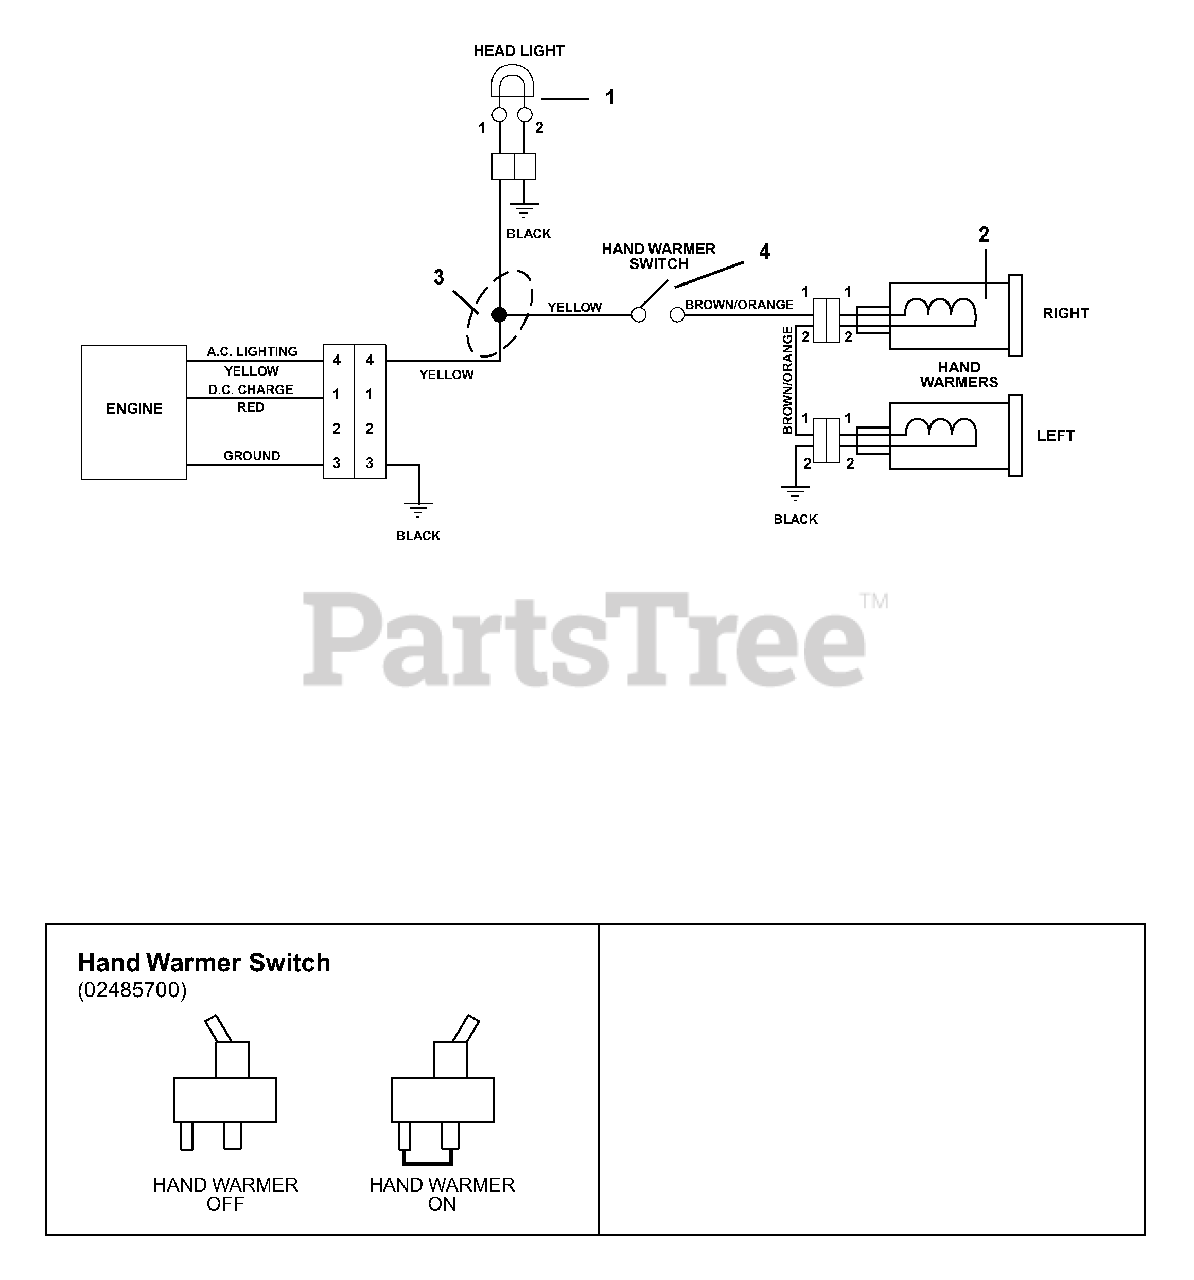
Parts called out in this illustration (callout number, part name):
1	LIGHT, HALOGEN ASSY.
2	WARMER, HAND W/TERMINAL
3	HARNESS, WIRE-LIGHT HANDWARMER
4	SWITCH, ON/OFF
02485700	SWITCH, ON/OFF
